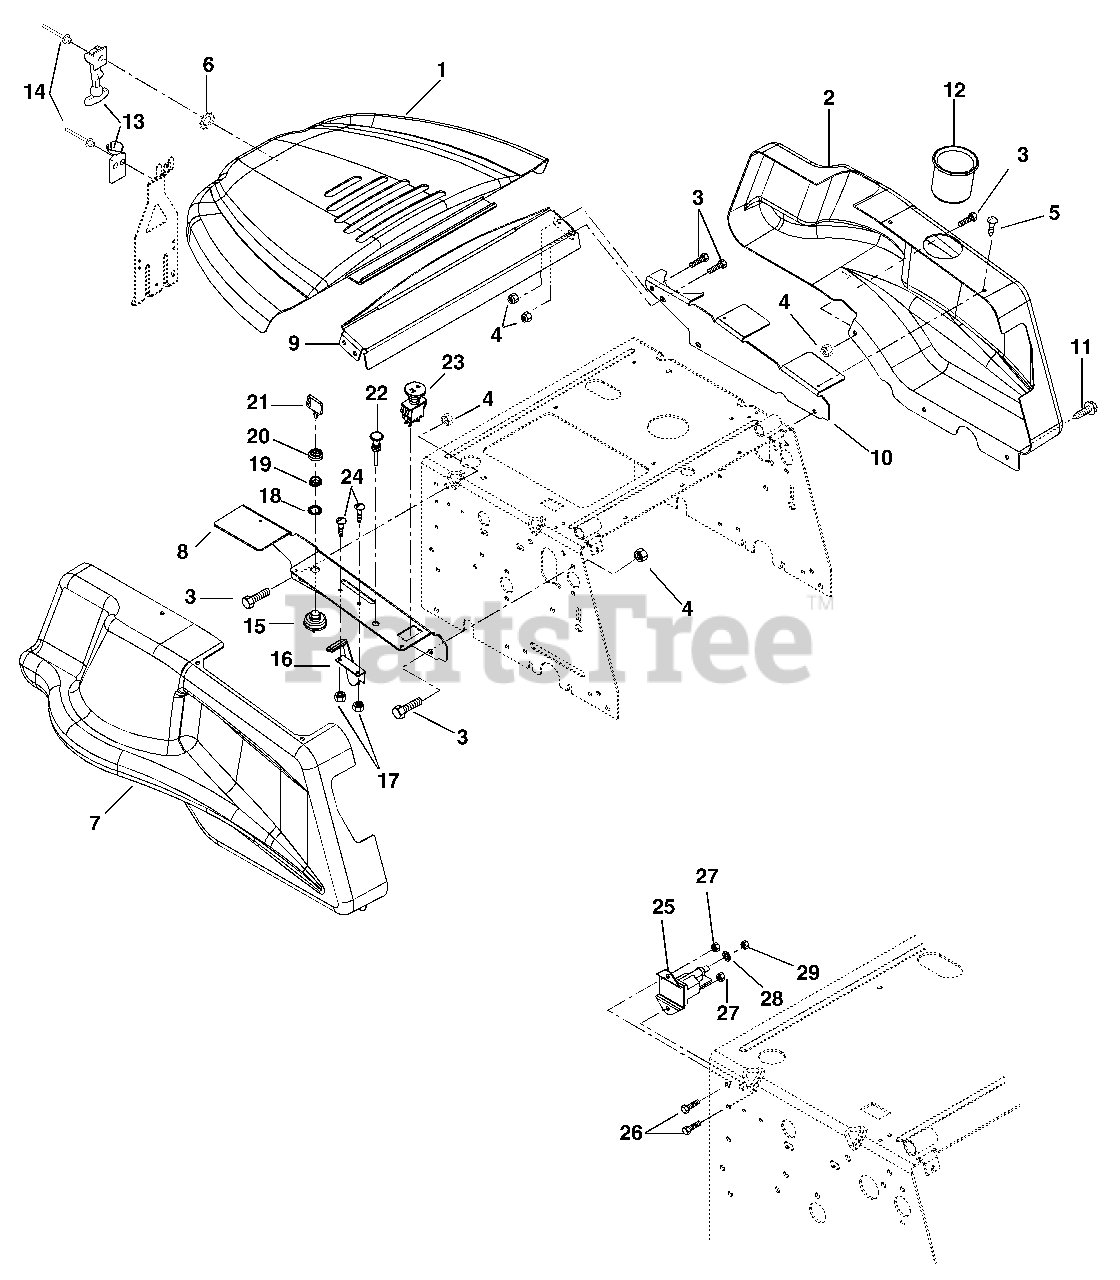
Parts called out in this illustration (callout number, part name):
1	SHROUD, TOP
2	SHROUD, SIDE LH
3	BLT SERHFWH .31-18X.62 GR5YWZC
4	@NUT-LK-TOP-FLG .31-18 YWZC
5	SCR-TAP #10-16 X .625 HWH
6	RVT-BURR .125X.505X.048
7	SHROUD, SIDE RH
8	CONTROL, BRACKET
9	HOOD, BRACKET
10	FUEL TANK, BRACKET
11	@SCR-TAP .31-18X.50 HWH TR YWZ
12	CUPHOLDER
13	LATCH,FLEXIBLE
14	RVT-POP.125 X .357 DOME PL
15	KEY SWITCH
15	SWITCH KEY 5Y463A ALT GRDNG
16	CABLE, THROTTLE 30.12
16	CABLE, THROTTLE 19.5
17	@NUT-LK-NYL 10-24 W/INSRT YWZC
18	WSHR-LK-INT .563X.040 YWZC
19	NUT- PANEL .562-24 GRECO
20	CAP - IGNITION SWITCH
21	KEY -W/CAP
22	CABLE, CHOKE
22	HOLE PLUG, PLASTIC .44 HOLE
23	SWITCH, CLUTCH
24	@SCR-MCH 10-24X.50 HWH YWZC
25	SOLENOID
26	@BLT-HEX .25-20X.50 GR5 YWZC
27	@NUT-LK-CTR .25-20 YWZC
28	WSHR-LOCK INT .31 YWZC
29	NUT-JAM .31-24 YWZC
